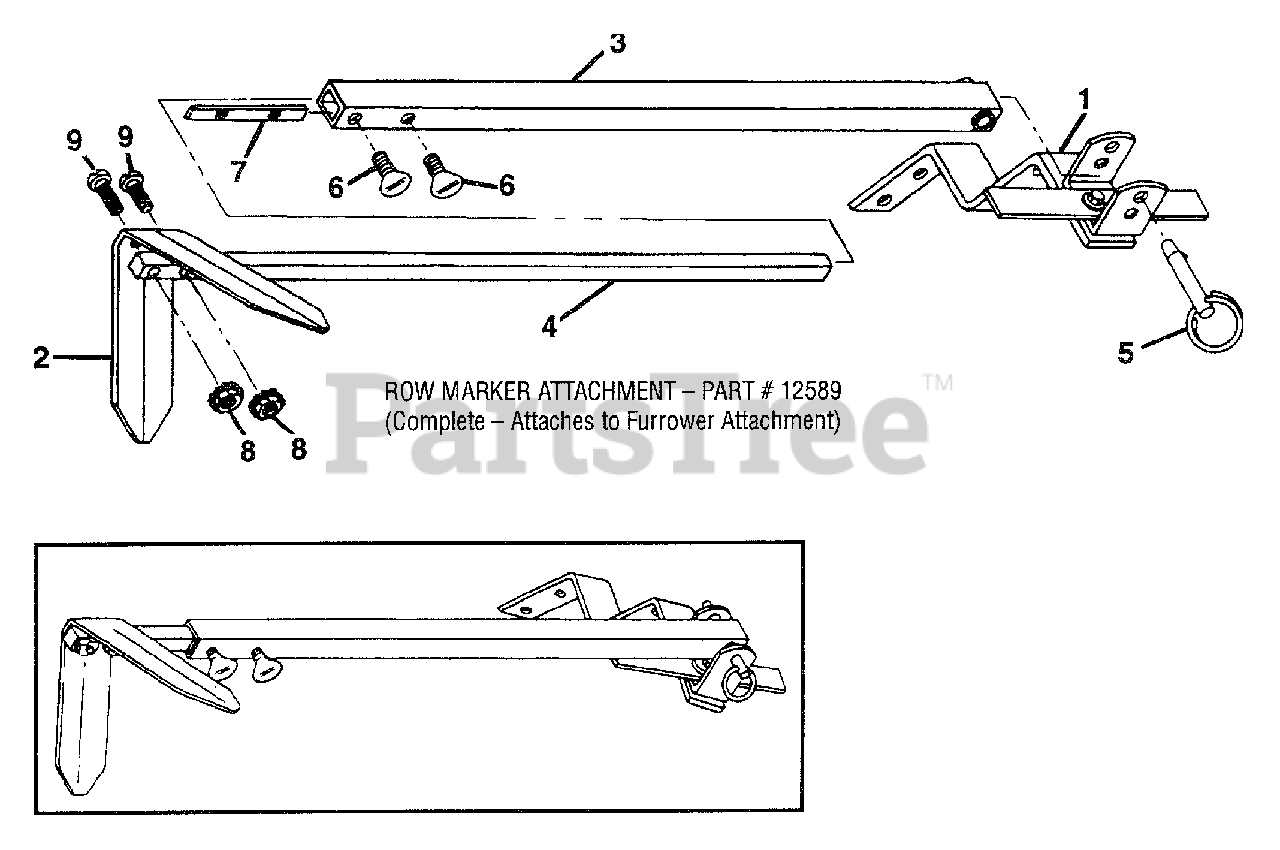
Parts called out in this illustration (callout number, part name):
1	Main Support & Yoke Assy-complete
2	Marker Blade-blade only
3	Marker Arm-main arm
4	Marker Arm-extension arm with stop pin
5	Hitch Pin-
6	Thumbscrew-1/4-20 x 1/2, not avail. sep.
7	Nut Bar-
8	Nut-hex, 10-24 w/attached start washers, not avail. sep.
9	Screw-round hd.,10-24 x 1, not avail. sep.
12589	Row Marker Attachment-
